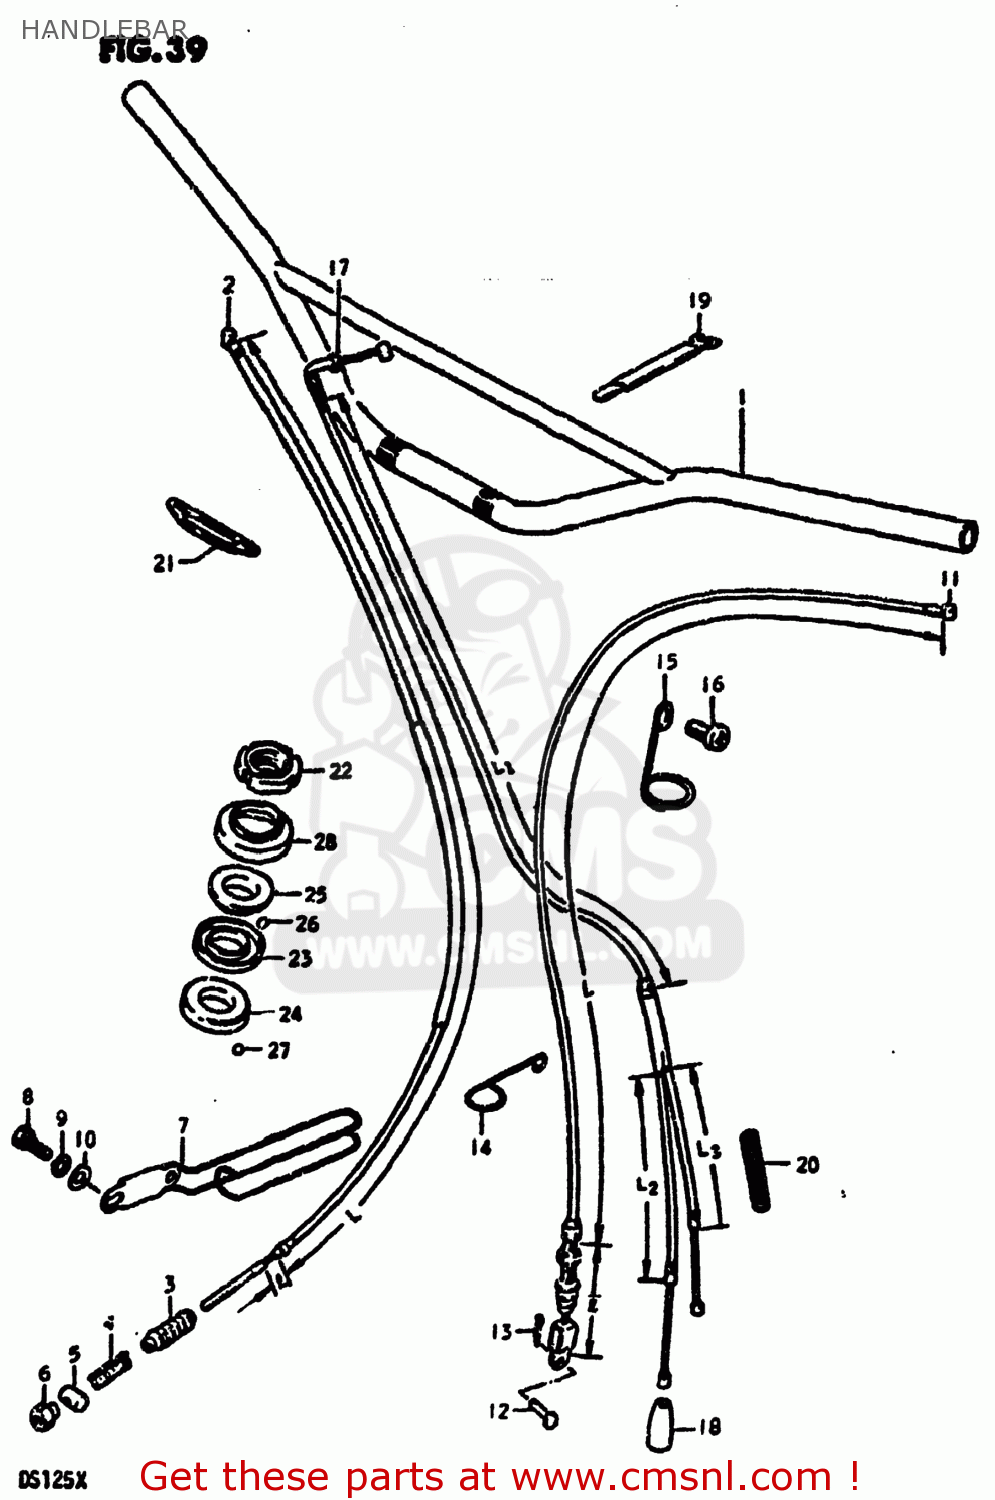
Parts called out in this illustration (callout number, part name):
1	HANDLEBAR
2	CABLE ASSEMBLY,FRONT BRAKE
3	SEAL,DUST(7X16X75)
4	SPRING
5	PIN,10X19
6	NUT
7	GUIDE,CABLE
8	BOLT 8X12
9	LOCK WASHER
10	WASHER
11	CABLE ASSEMBLY,CLUTCH
12	PIN(L:15)
13	PIN
14	CLAMP
15	CLIP
16	SCREW
17	CABLE ASSEMBLY,THROTTLE
18	SEAL,DUST(7X18X30)
19	CLAMP L:110
20	PROTECTOR,CABLE
21	GUIDE,CABLE
22	NUT,STEERING STEM(25X44X10)
23	RACE,STEERING INNER UPR
24	LACE,STEERING INNER LWR
25	RACE,STEERING OUTER UPR
26	BALL
27	BALL
28	DUST SEAL,STEERING UPR
